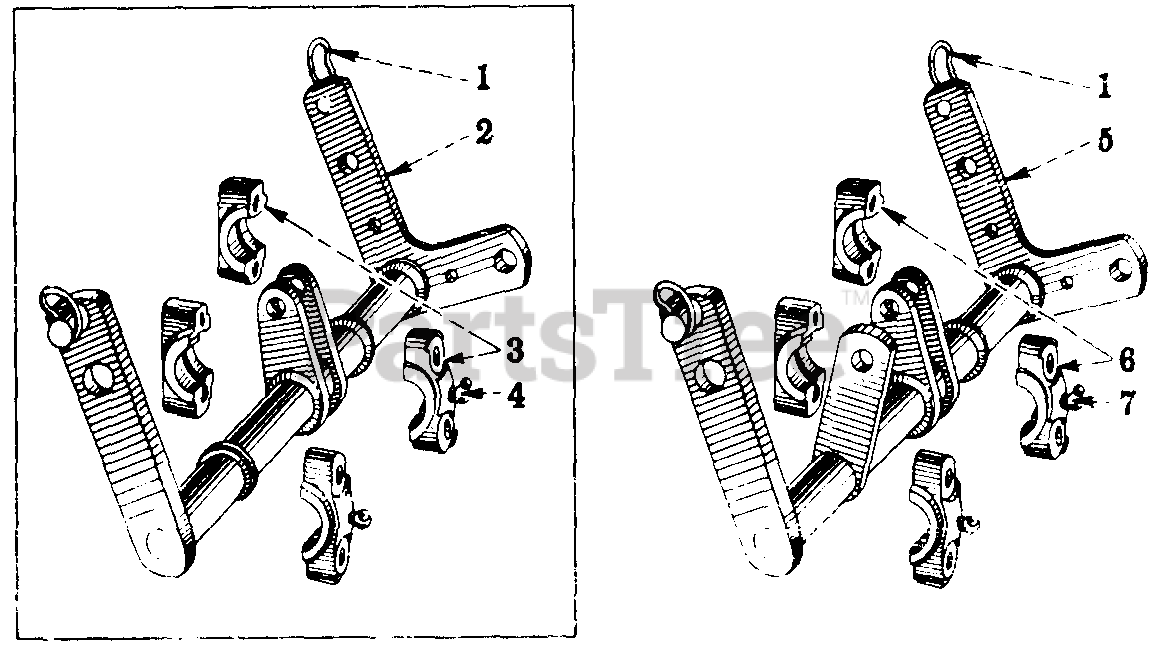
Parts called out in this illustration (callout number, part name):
1	PIN, QUICK ATTACHABLE COT
2	ROCKSHAFT ASSY
3	BEARING ASSY, ROCKSHAFT
4	FITTING, 1/8 X 67-1/2 DEG ELBOW LUB
5	ROCKSHAFT ASSY
6	BEARING ASSY, ROCKSHAFT
7	FITTING, 3/16 X 65 DEG ELBOW DRIVE TYPE LUB
